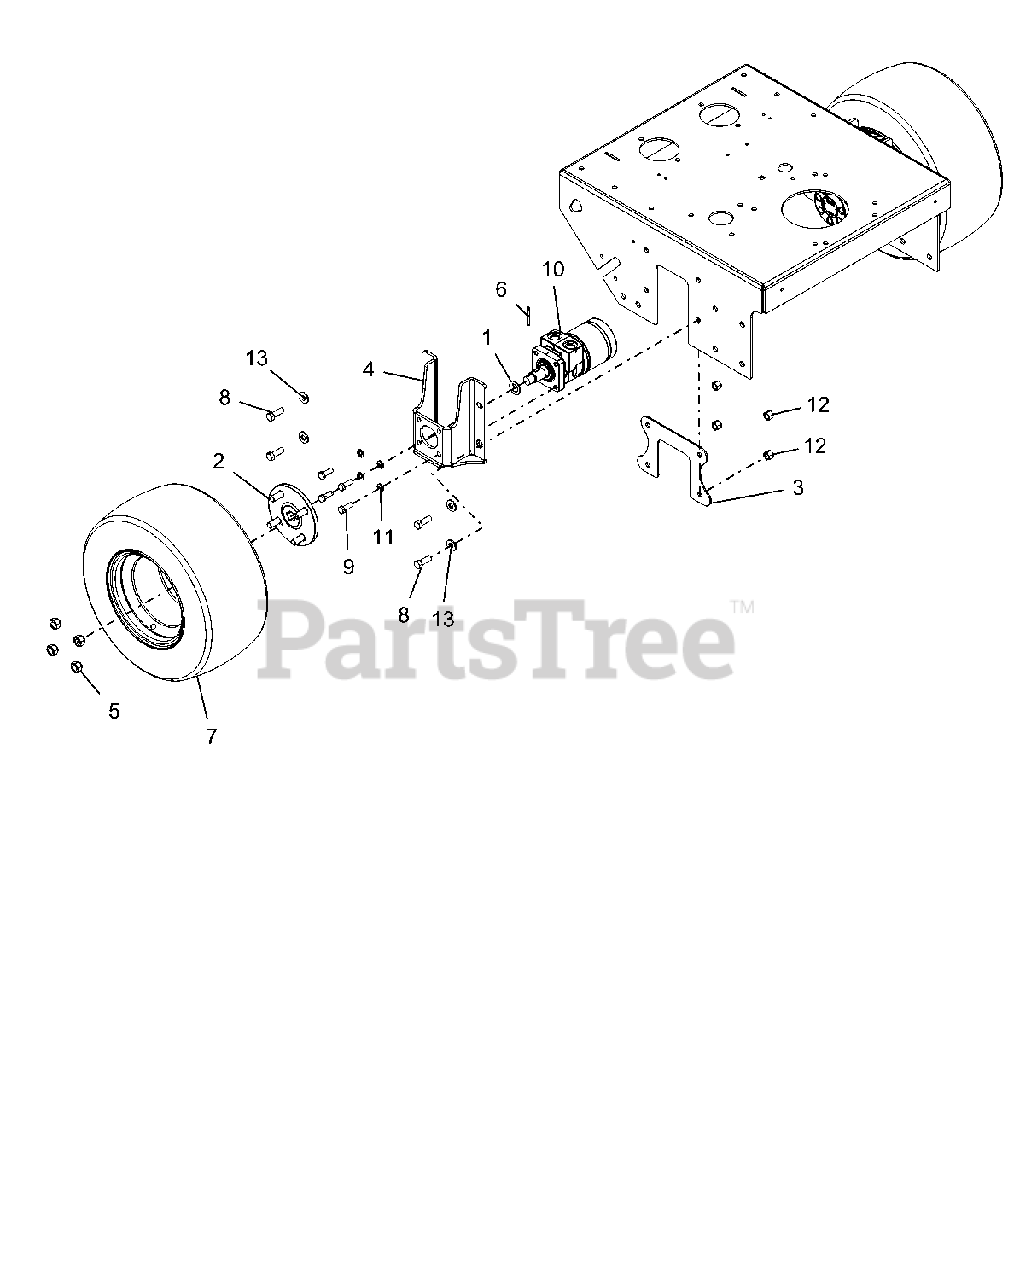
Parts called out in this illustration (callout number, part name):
1	BUSHING, MACH .75 X 1.25 X .048
2	ASSY, WHEEL HUB
3	PLATE, ENGINE BED DOUBLE-RED
4	WLDMT, WHEEL MOTOR BRACKET-RED
5	NUT, 1/2-20 LUG C
6	PIN, COTTER
7	ASSM, WHL/TIRE 16X7.50-8 K500
8	BLT-HEX .44-14X1.25 GR5 YWZC
9	BOLT, 3/8-16 X 1 GR8 BLACK
10	MOTOR, HYDRAULIC WHEEL
11	WSHR-LK .38X.094 REG YWZC
12	NUT-LK-NYL .44-14 YWZC
13	WSHR-FL-STL .468X1.00X.125 YWZC
